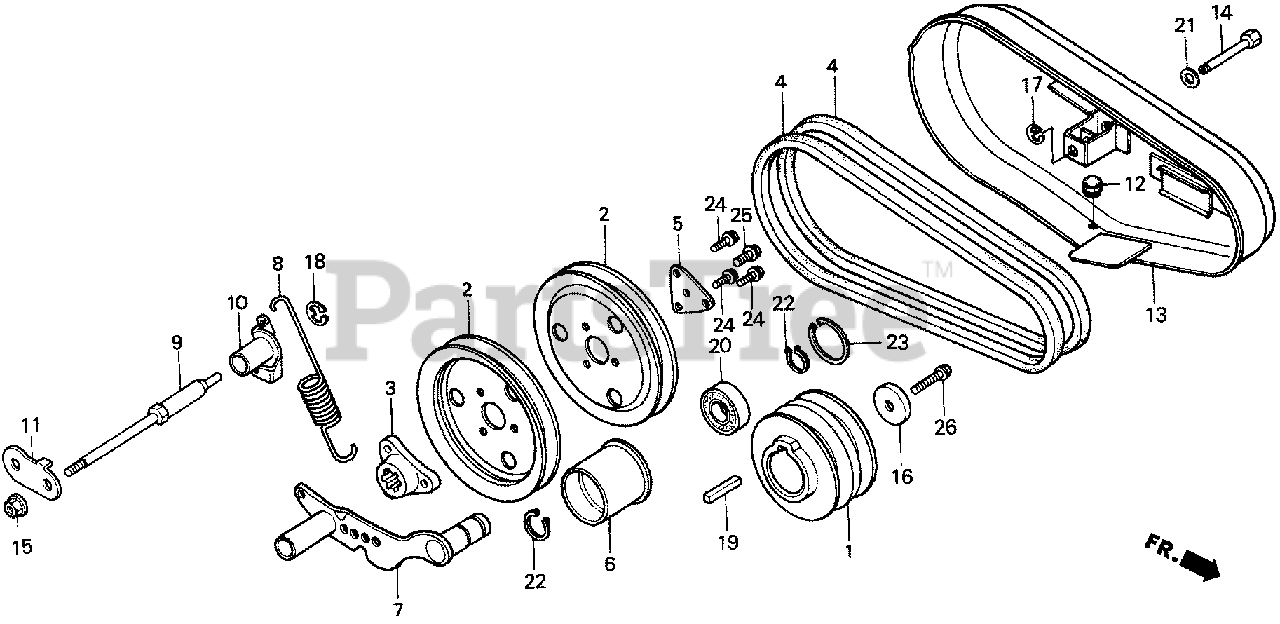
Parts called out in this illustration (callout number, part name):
1	PULLEY, DRIVEN (80MM) (NOT AVAILABLE)
2	PULLEY (156MM)
3	BOSS, DRIVEN PULLEY
4	V-BELT (35)
5	PLATE, PULLEY
6	ROLLER, TENSIONER
7	ARM, TENSIONER
8	SPRING, BELT TENSIONER
9	SHAFT, CLUTCH LINK
10	LINK, CLUTCH
11	STAY D, CLIP
12	STOPPER, TENSIONER ARM
13	COVER, BELT
14	LATCH, BELT COVER
15	NUT, FLANGE (8MM)
16	WASHER, LOCK (8MM)
17	E-RING (9MM)
18	E-RING (10MM)
19	KEY (7X7X33)
20	BEARING, RADIAL BALL (6202G)
21	WASHER, PLAIN (10MM)
22	CIRCLIP (OUTER) (15MM)
23	CIRCLIP (INNER) (35MM) (NOT AVAILABLE)
24	BOLT, FLANGE (6X16)
25	BOLT, FLANGE (8X16)
26	BOLT, FLANGE (8X28)
